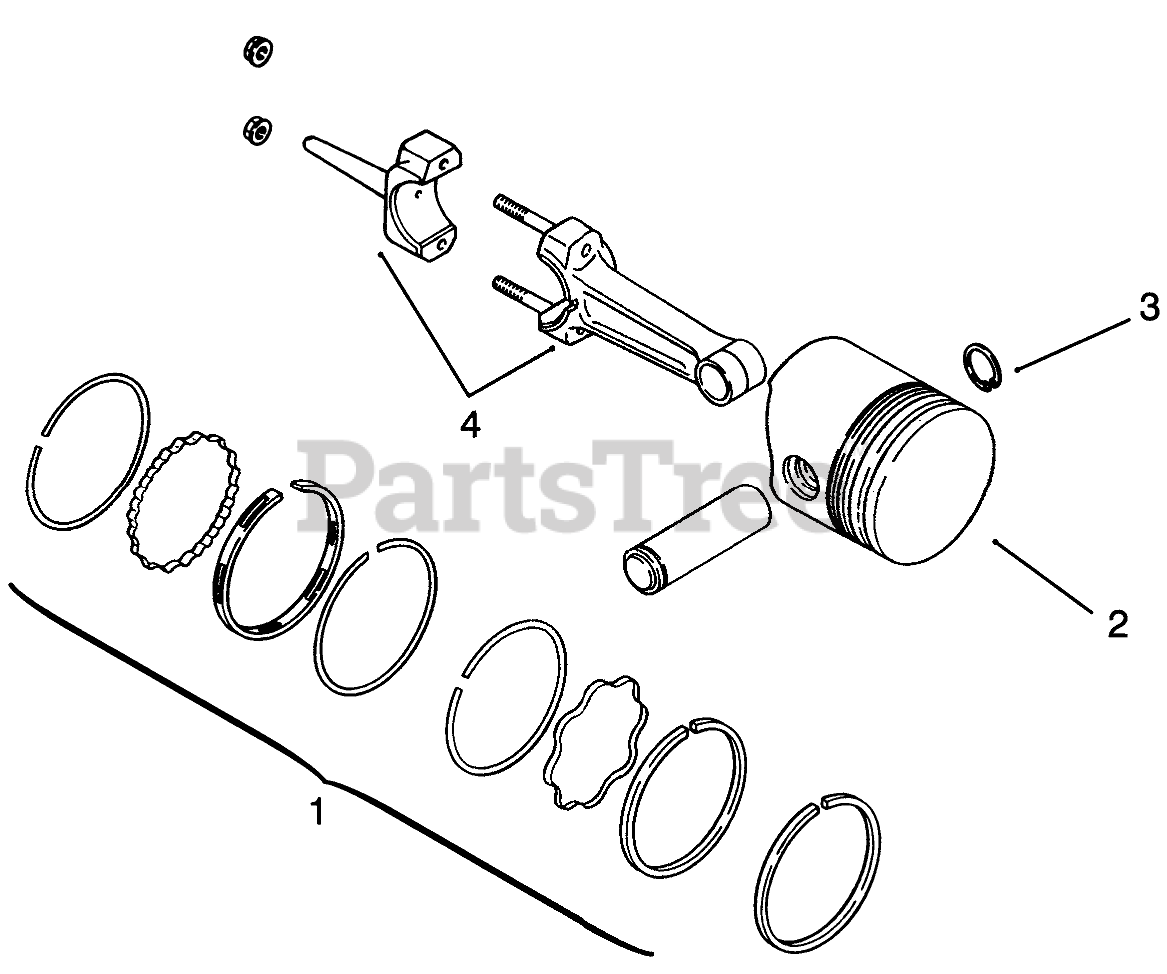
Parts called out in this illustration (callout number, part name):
1	Set-Ring, Std. &.003
2	Piston w/Ring Set Std.
3	Piston Pin Retainer
4	Rod-Connecting Std.
